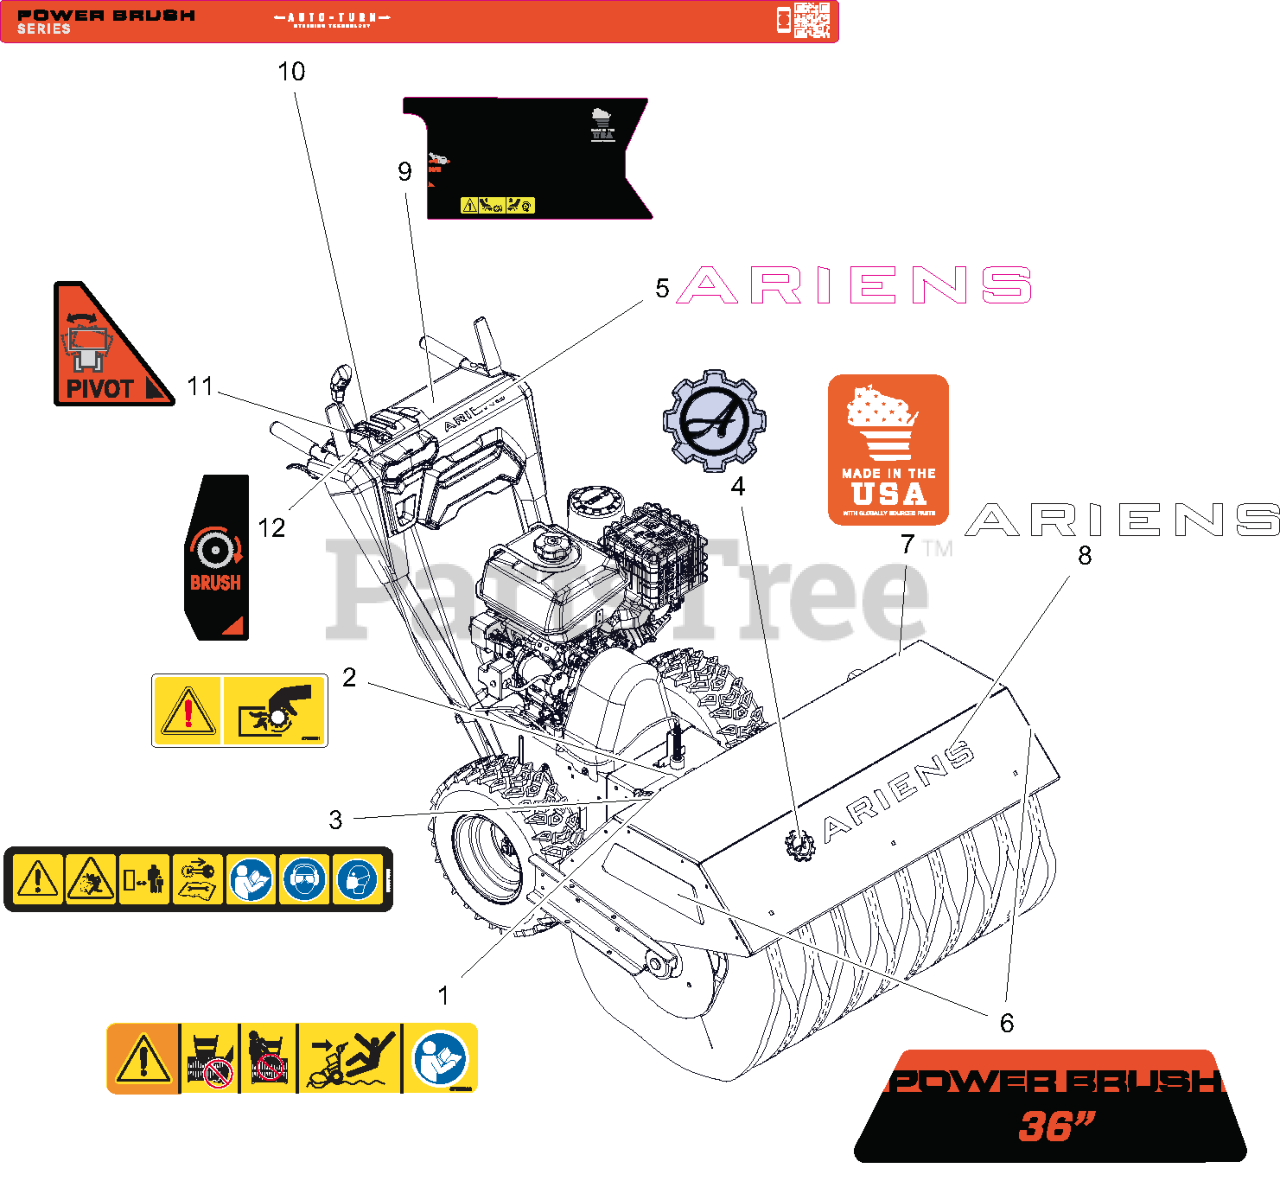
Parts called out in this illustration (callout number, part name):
1	DECAL, DANGER -POWER BRUSH-CE
2	DECAL, PTO WARNING
3	DECAL, SAFETY, DASH, BRUSH
4	DECAL, ARIENS - GEAR BADGE
5	DECAL- ARIENS - 7.46"
6	DECAL, POWERBRUSH - 36
7	DECAL- MADE IN USA
8	DECAL, ARIENS - 19.0"
9	DECAL, CONTROL - LG BRUSH
10	DECAL, DASH - BRUSH
11	DECAL, CONTROL - BRUSH PIVOT
12	DECAL, CONTROL - BRUSH
